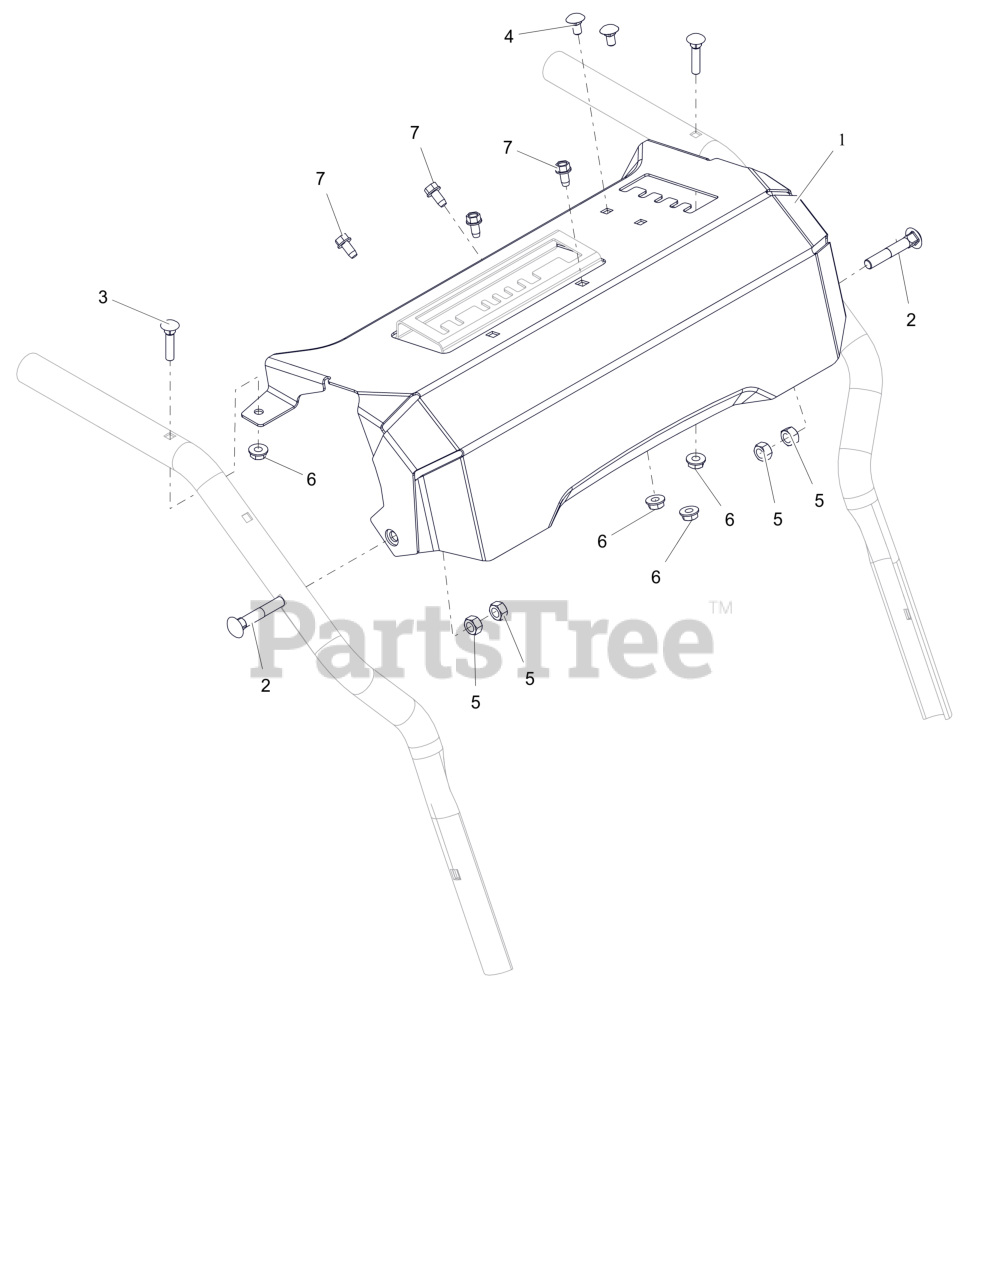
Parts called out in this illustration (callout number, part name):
1	PANEL, DASH - CLASSIC W/DECALS
2	BLT-RDHDXLSQNK .31-18X2.0 G5YZ
3	BLT-RDHDXLSQNK.25-20X1.25 G5ZC
4	BLT, RHSN .25-20X.500 G5 ZCC
5	NUT,LK-CTR .31-18 GA ZCC
6	NUT-LK-CTR-FLG .25-20 ZC120
7	SCR-TAP .25-20X.50 HWH ZCC
